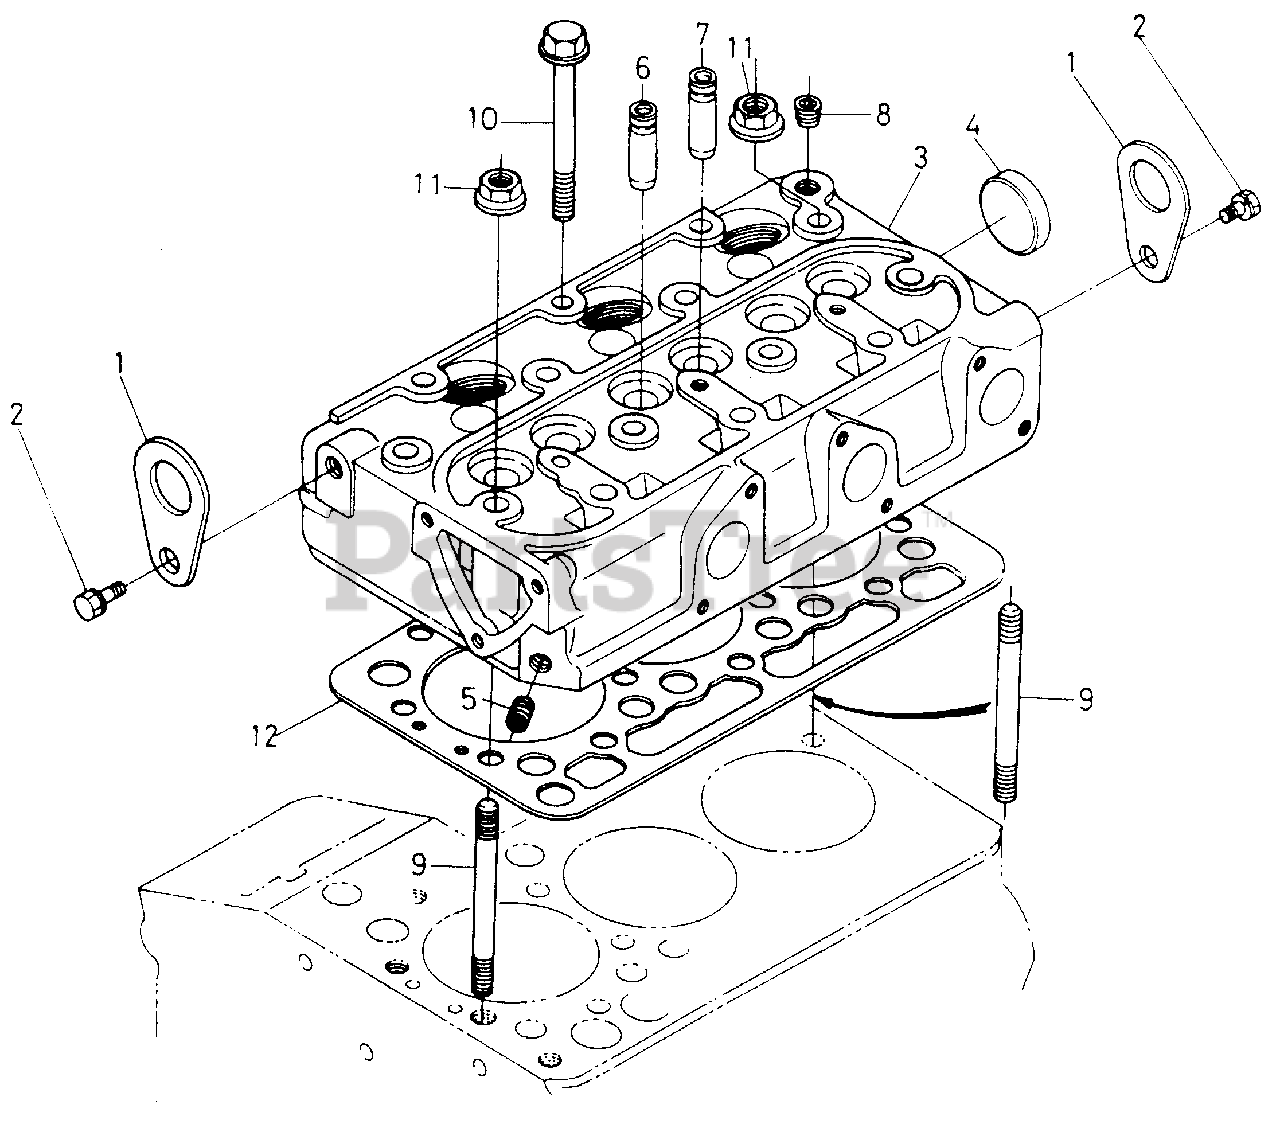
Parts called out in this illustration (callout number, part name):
2	Bolt, M8 X 14 Pln H/Hd Class 8.8
3	Head Assy, Cylinder
6	Guide, Intake Valve
7	Guide, Exhaust Valve
8	Plug
12	Gasket, Head
